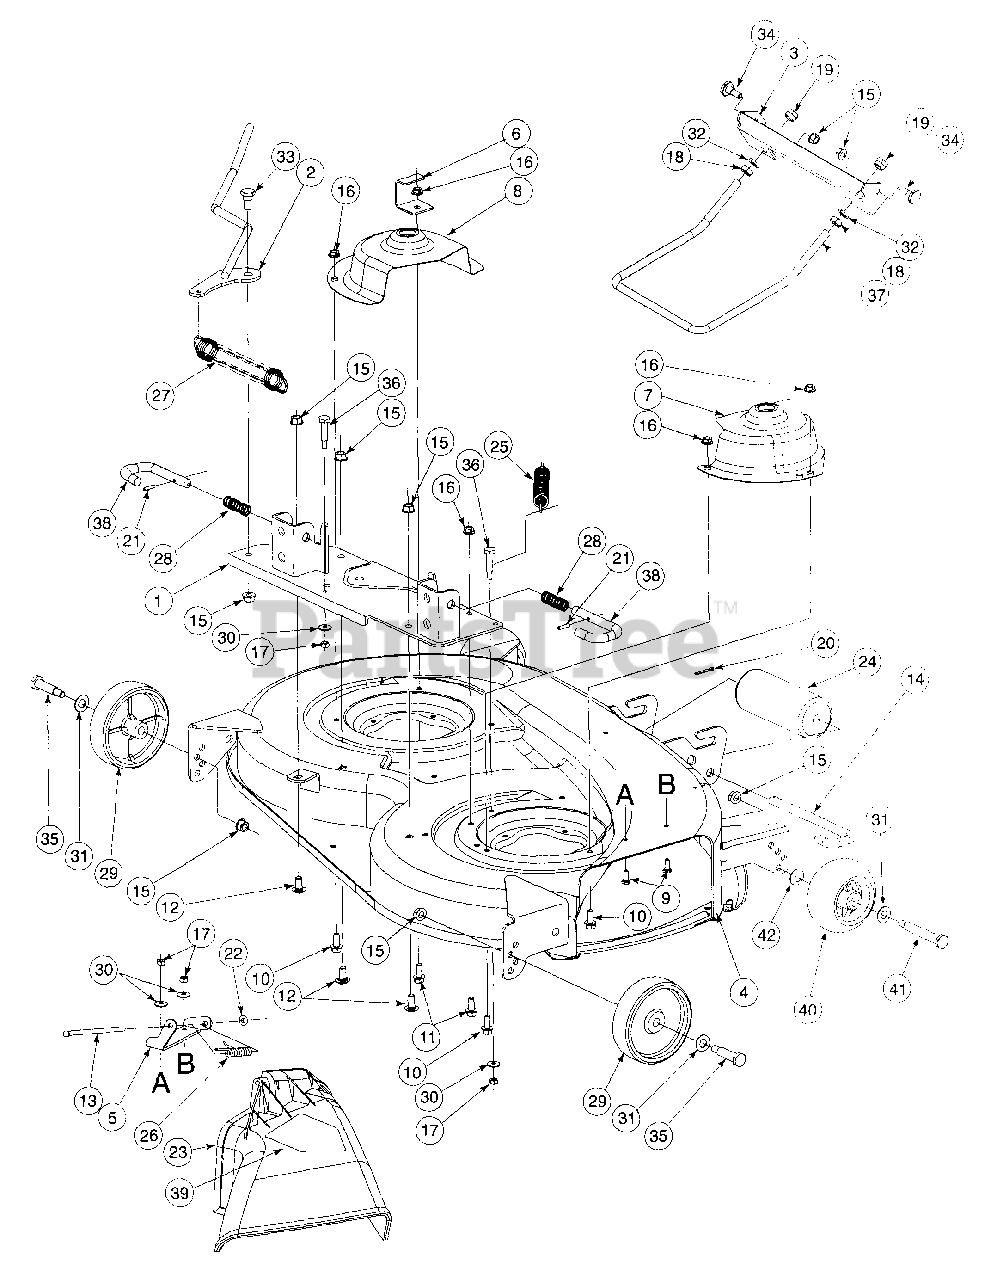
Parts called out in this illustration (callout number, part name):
1	Plate Assembly, Mounting
3	Bracket, Front Lift
4	Deck Assembly, 38" w/out Front Wheels
4	Deck Assembly, 38" w/Front Wheels
4	Graphic, Danger Top/RH Deck
4	Graphic, Tension Lever
4	Graphic, Safety Top/LH Deck
4	Graphic, Assembly Chute
5	Bracket, Hinge Mounting
6	Bracket, Handle Stop
7	Shield, RH Pulley
8	Shield, LH Pulley
9	Screw, Hex Cap, 1/4-20 x .62
10	Screw, Hex Wash Hd Tapp 5/16-18 x .75
11	Screw, Hex Cap 5/16-18 x .75 GR5
12	Bolt, Carriage, 3/8-16 x .75
13	Pin, Hinge, .25 Dia x 6.75 Lg
14	Pin, Roller, 1/2 Dia x 7.31 Lg
15	Nut, Hex Flange Lock, 3/8-16
16	Nut, Hex Flange Lock 5/16-18 GR5
17	Nut, Hex, 1/4-20
18	Nut, Hex Jam, 1/2-13 GR5
19	Nut, Hex Insert Lock, 1/2-13
20	Pin, Cotter, 3/32 x 1.25
21	Pin, Spirol Spring, 3/16 x .75
22	Cap, Speed Nut
23	Deflector Assy, Chute
25	Spring, Extension, .88 OD x 6.12
26	Spring, Torsion
27	Spring, Extension, 1.25 OD x 8.15
28	Spring, Compression
29	Wheel, Deck, 5 in. Dia
30	Washer, Bell, .265 x .75 x .062
31	Washer, Flat, .510 x 1.0 x .060
32	Washer, Lock, 1/2
33	Bolt, Shoulder, .498 Dia x .340 Lg
34	Bolt, Shoulder, .50 Dia x .434 Lg
35	Bolt, Shoulder, .498 Dia x 1.64 Lg
36	Bolt, Shoulder, .375 Dia x 1.16 Lg
37	Rod, Front Lift
38	Pin, Mower Support
39	Graphic, Danger
40	Wheel, Deck w/Fitting
40	Lube Fitting
41	Bolt, Shoulder, 1/2 x 2.5
42	Washer, Bell, .401 x .870 x .063
